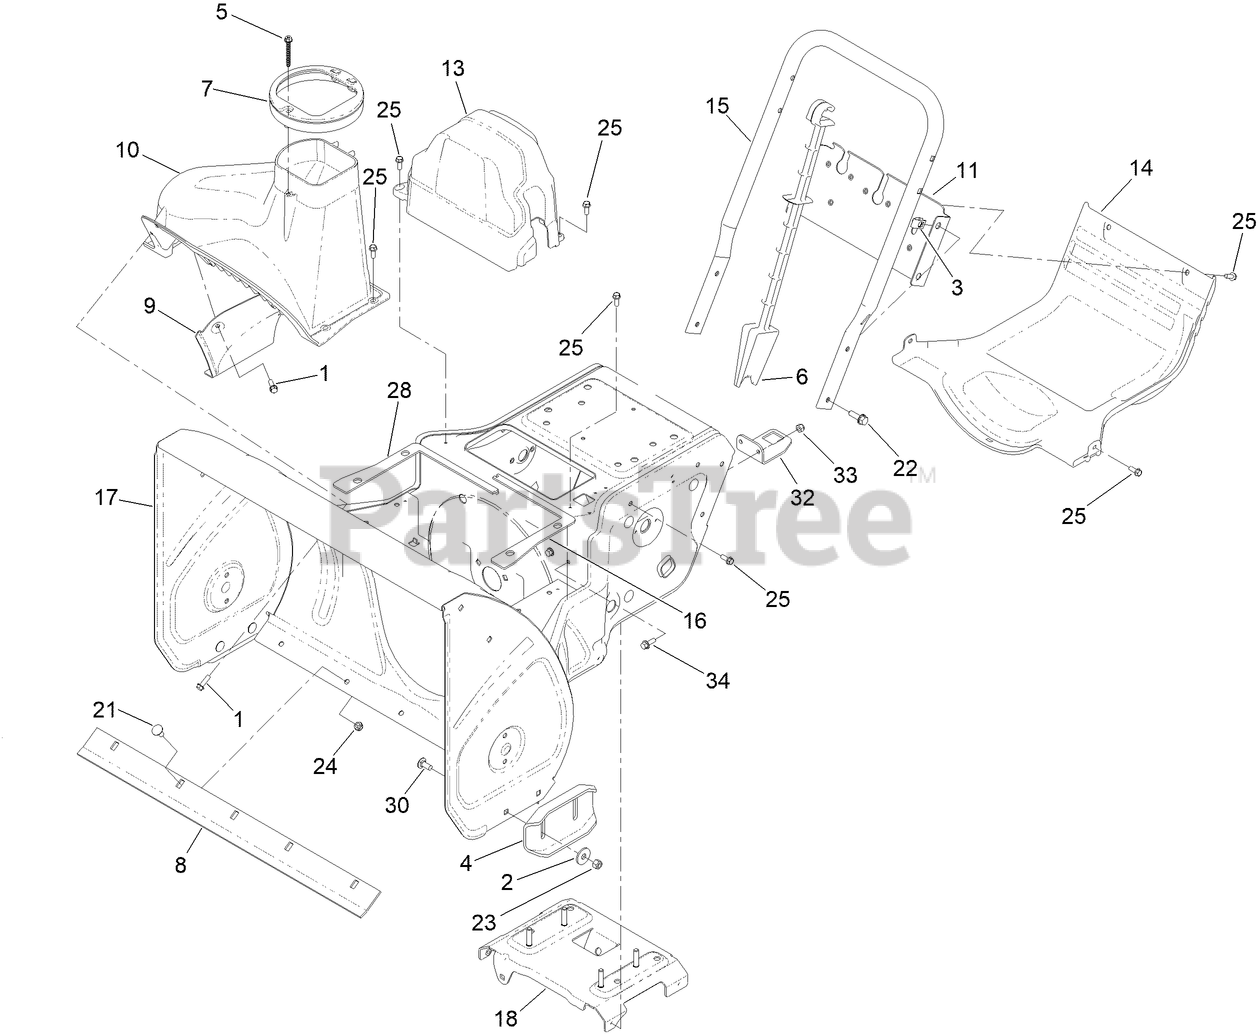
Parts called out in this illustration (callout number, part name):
1	SCREW-PLASTITE, HWH
2	WASHER-FLAT
3	NUT-U
5	SCREW-HWH, PLASTITE
6	STICK-CLEANOUT
7	GUIDE-CHUTE
8	SCRAPER-26 INCH
9	COVER-LINER
11	BRACE-FRAME
13	COVER-BELT
14	COVER-LOWER
15	HANDLE-LOWER, CTS
16	SEAL-HOUSING, LH
17	FRAME ASM
18	BRACE-FRAME
21	BOLT-CARR
22	SCREW-HHF
23	NUT-HEX
24	NUT-HEX
25	SCREW-HWH
28	SEAL-HOUSING, RH
30	BOLT-CARR
32	BRACKET-POST, CHUTE
33	SCREW-HHF
34	NUT-HEX
